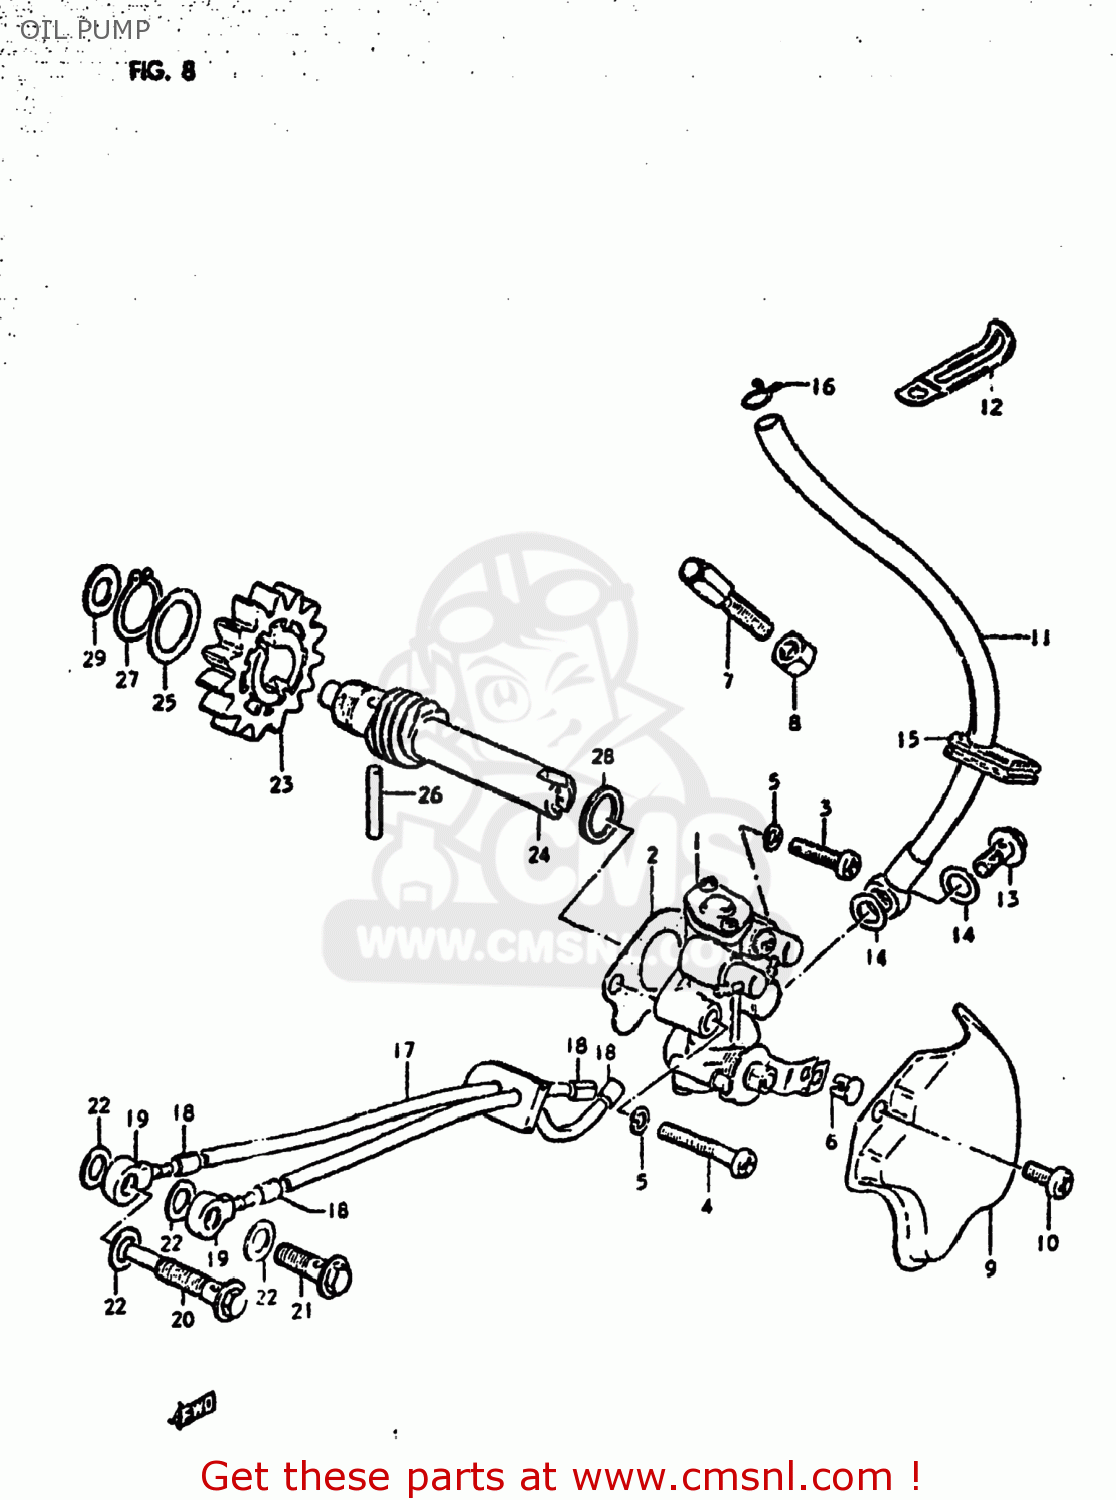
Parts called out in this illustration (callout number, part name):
1	PUMP ASSEMBLY,OIL
2	GASKET,OIL PUMP (NAS)
3	SCREW
4	SCREW
5	LOCK WASHER
6	TERMINAL,CABLE
7	BOLT
8	NUT
9	CAP,OIL PUMP INSPECTION
10	SCREW
11	HOSE,OIL NO.1
12	CLAMP
13	UNION BOLT
14	GASKET(6.2X11X1).2 (NAS)
15	GROMMET
16	CLIP
17	HOSE,OIL NO.2
18	CLIP
19	UNION
20	UNION
21	UNION BOLT
22	GASKET(6.2X11X1).2 (NAS)
23	GEAR,OIL PUMP DRIVE
24	SHAFT,OIL PUMP IDLE GEAR
25	WASHER, INNER
26	ROLLER(4X23.8)
27	CIRCLIP
28	WASHER
29	THRUST WASHER
